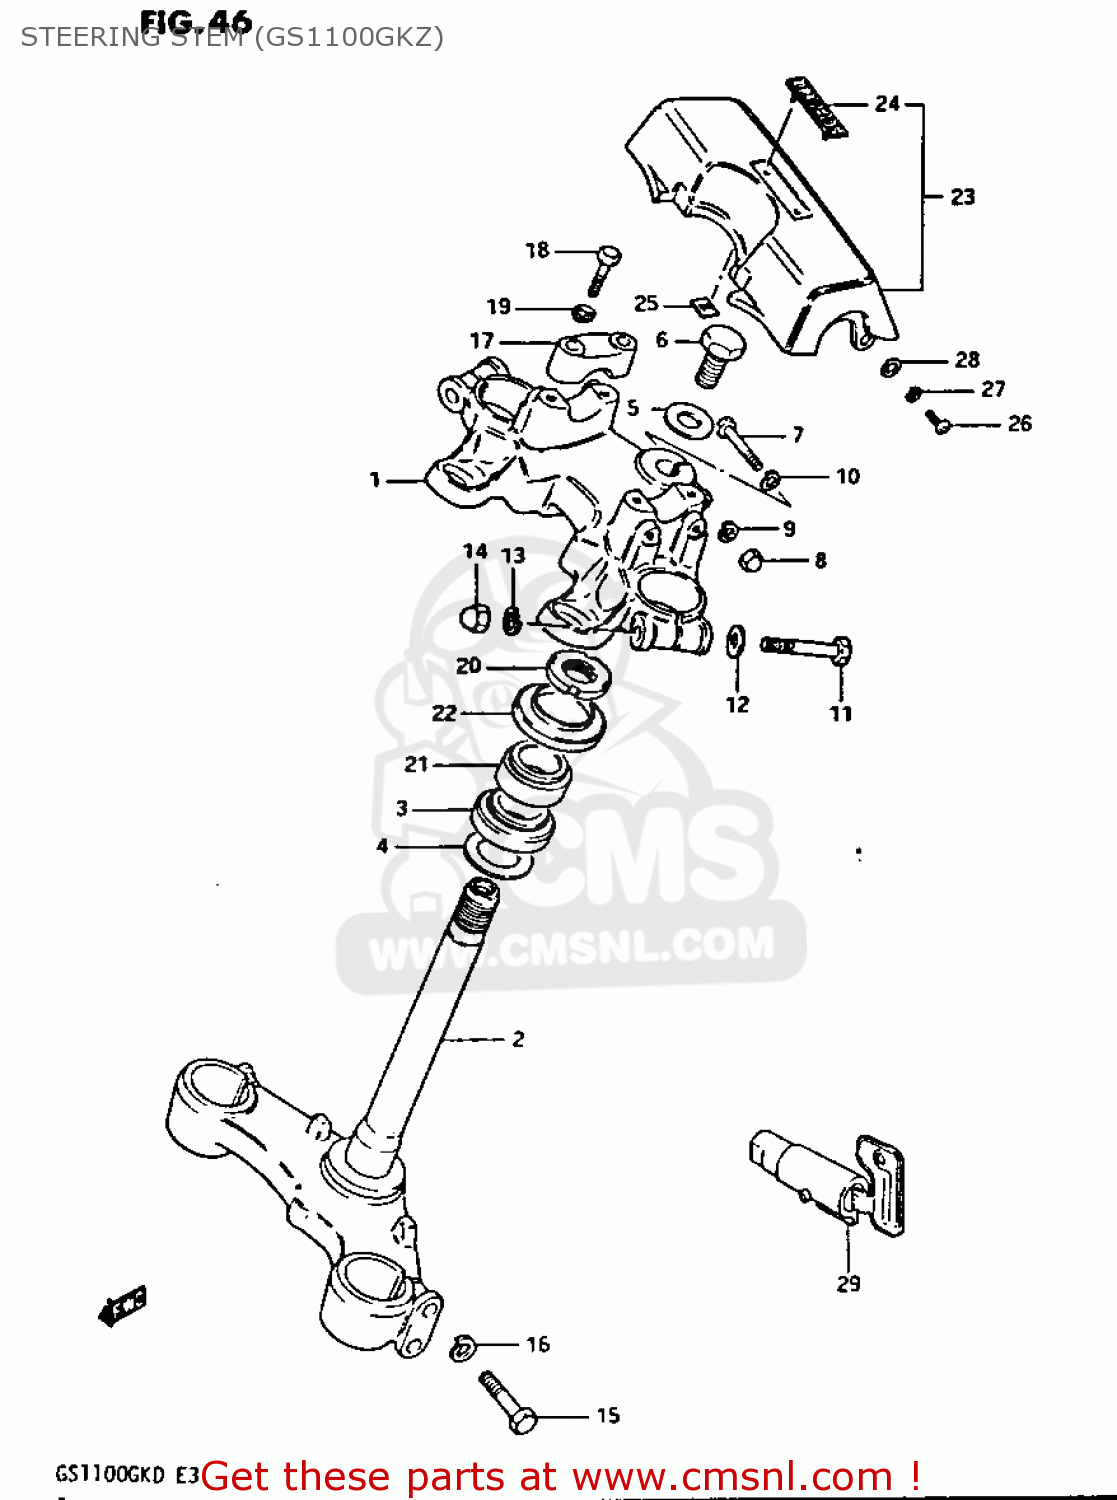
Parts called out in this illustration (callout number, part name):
1	HEAD,STEERING STEM
2	STEM,STEERING
3	BEARING(30X55X17)
4	WASHER,THRUST
5	WASHER,STEERING STEM
6	NUT,STEM HEAD
7	BOLT 8X50
8	NUT
9	LOCK WASHER
10	WASHER
11	BOLT 10X55
12	WASHER
13	WASHER,LOCK,10
14	NUT
15	BOLT 8X40
16	LOCK WASHER
17	HOLDER,HANDLE(BLACK)
18	BOLT
19	LOCK WASHER
20	NUT,STEERING STEM
21	TAPER,ROLLER BEARING
22	DUST SEAL,STEERING UPR
23	PAD,HANDLEBAR
24	EMBLEM,HANDLE COVER PAD
25	NUT
26	SCREW
27	LOCK WASHER
28	WASHER
